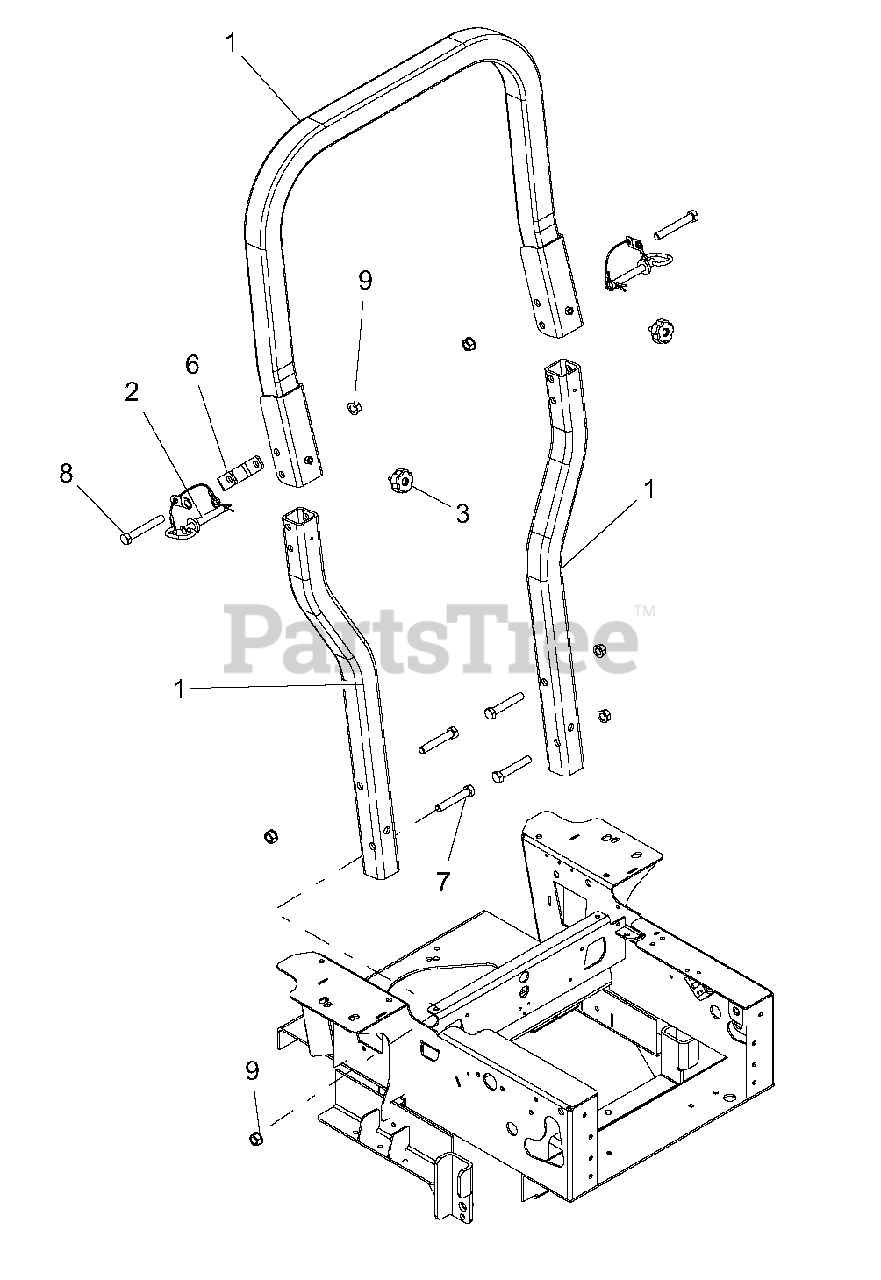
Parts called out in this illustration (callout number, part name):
1	WLDMT, ROPS HOOP, PT100
2	ASSY, ROPS PIN/LANYARD
3	KNOB, ROUND 5/16-18 X .750
6	BRKT, ROPS STOP, PRO-TURN
7	BLT-HEX .50-13X3.00 GR5 YWZC
8	BLT-HEX .50-13X3.50 GR5 YWZC
9	NUT, LK-TOP-FLG .50-13 YWZC
